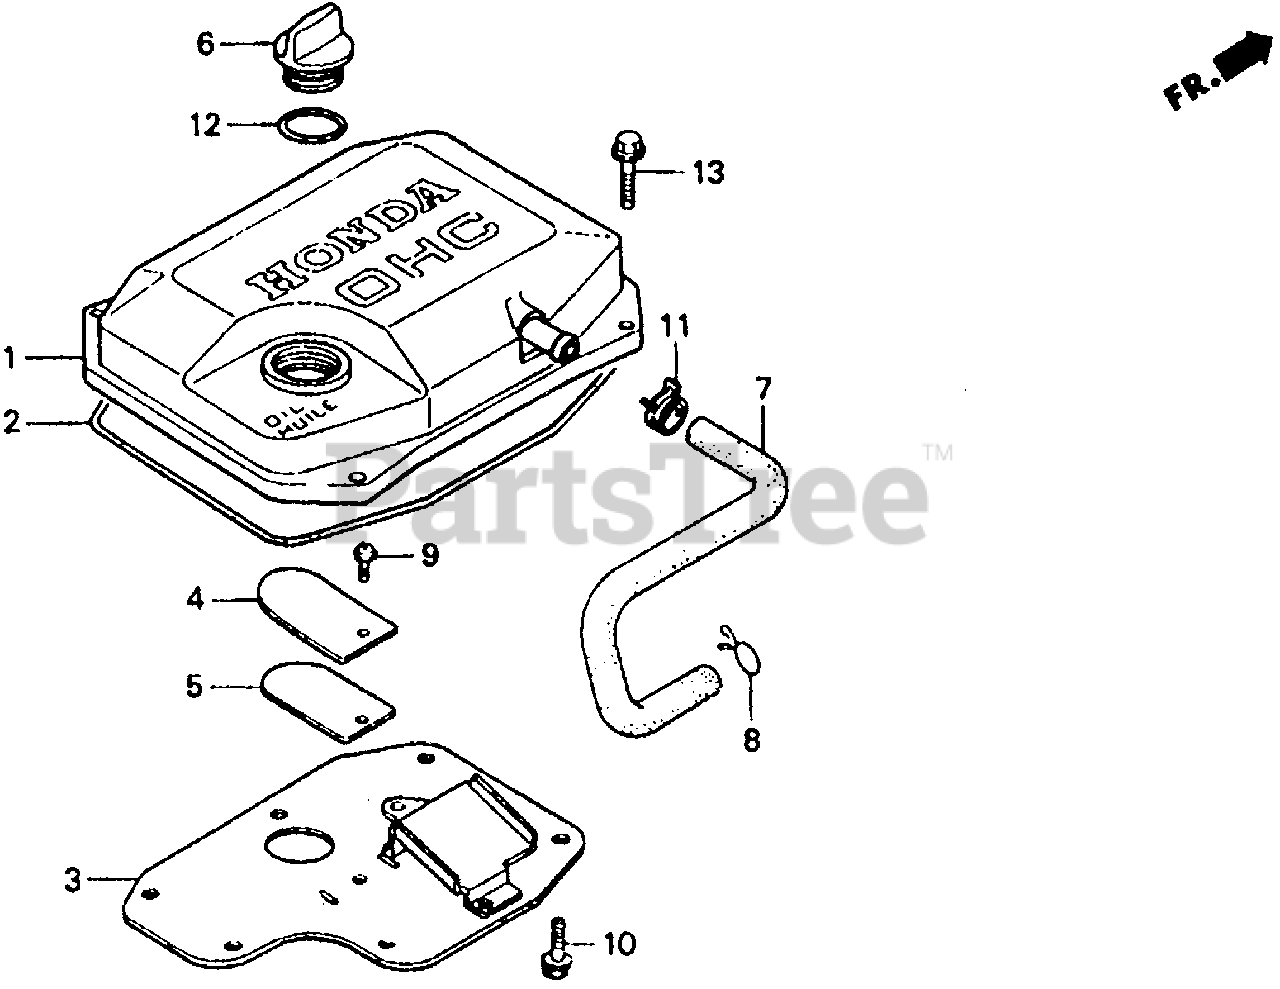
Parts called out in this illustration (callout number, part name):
1	COVER, CYLINDER HEAD
2	GASKET, HEAD COVER
3	COVER, BREATHER
4	STOPPER, VALVE
5	PLATE, VALVE
6	CAP, OIL (GRAY)
6	CAP, OIL
7	TUBE C, BREATHER
8	CLIP, BREATHER TUBE
9	SCREW-WASHER (5X8)
10	BOLT, FLANGE (6X10)
11	CLAMP, CANISTER HOSE
12	O-RING (26X2.7)
13	BOLT, FLANGE (6X25)
